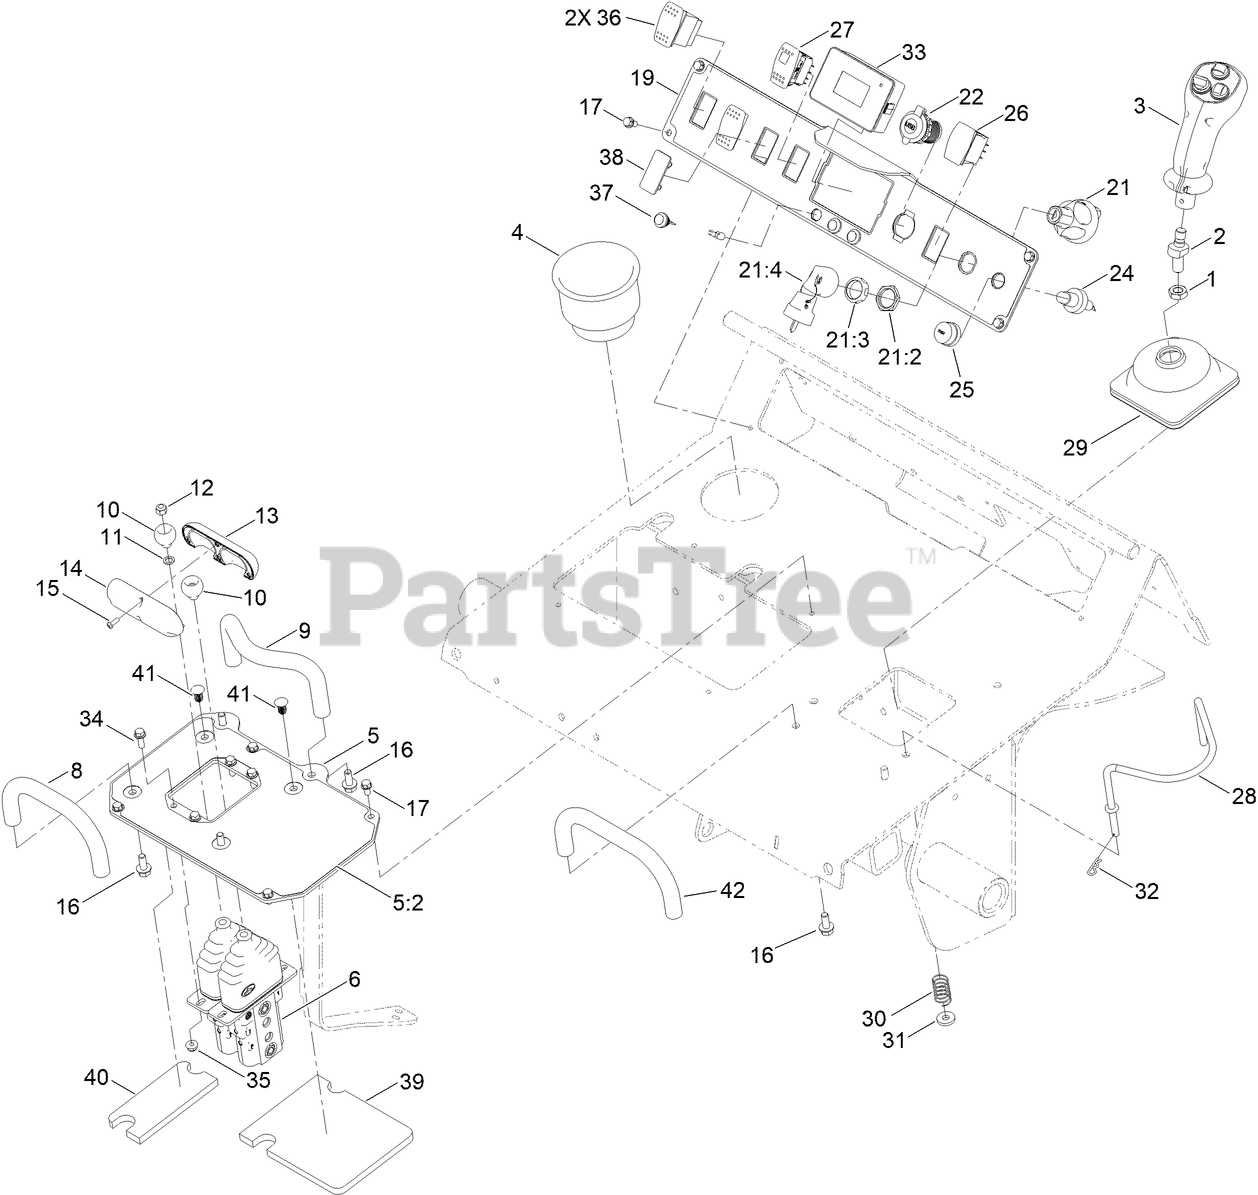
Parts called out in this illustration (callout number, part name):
2	SHAFT-CONTROL
3	HANDLE-JOYSTICK,
4	CUP-HOLDER
5	PLATE-CONTROL
5:2	DECAL-CONTROL PANEL
6	VALVE-CONTROL (TRACTION)
8	BAR-REFERENCE
9	BAR-REFERENCE
10	BALL-TRACTION
11	SPACER-BEARING
12	NUT-LOCK, NI
13	HANDLE-CONTROL
14	HANDLE-TRACTION
15	SCREW
16	SCREW-HHF
17	SCREW-HWH
19	PLATE-CONTROLS,
21	IGNITION SWITCH ASM
21:2	NUT-HEX
21:3	NUT-FACE
21:4	SET-KEY, IGNITION
22	SOCKET-USB
24	SWITCH-HORN
25	NUT-WEATHERPROOF
26	SWITCH
27	SWITCH
28	ROD-INTERLOCK
30	SPRING-CONTROL
31	WASHER-FLAT
33	TDM 2002
34	SCREW-HHF
35	NUT-HF
36	SWITCH
37	SWITCH-PUSHBUTTON
38	PLUG-HOLE
39	FOAM-SHIELD, HEAT
40	FOAM-SHIELD, HEAT
41	RIVET-PUSH
42	BAR-REFERENCE
